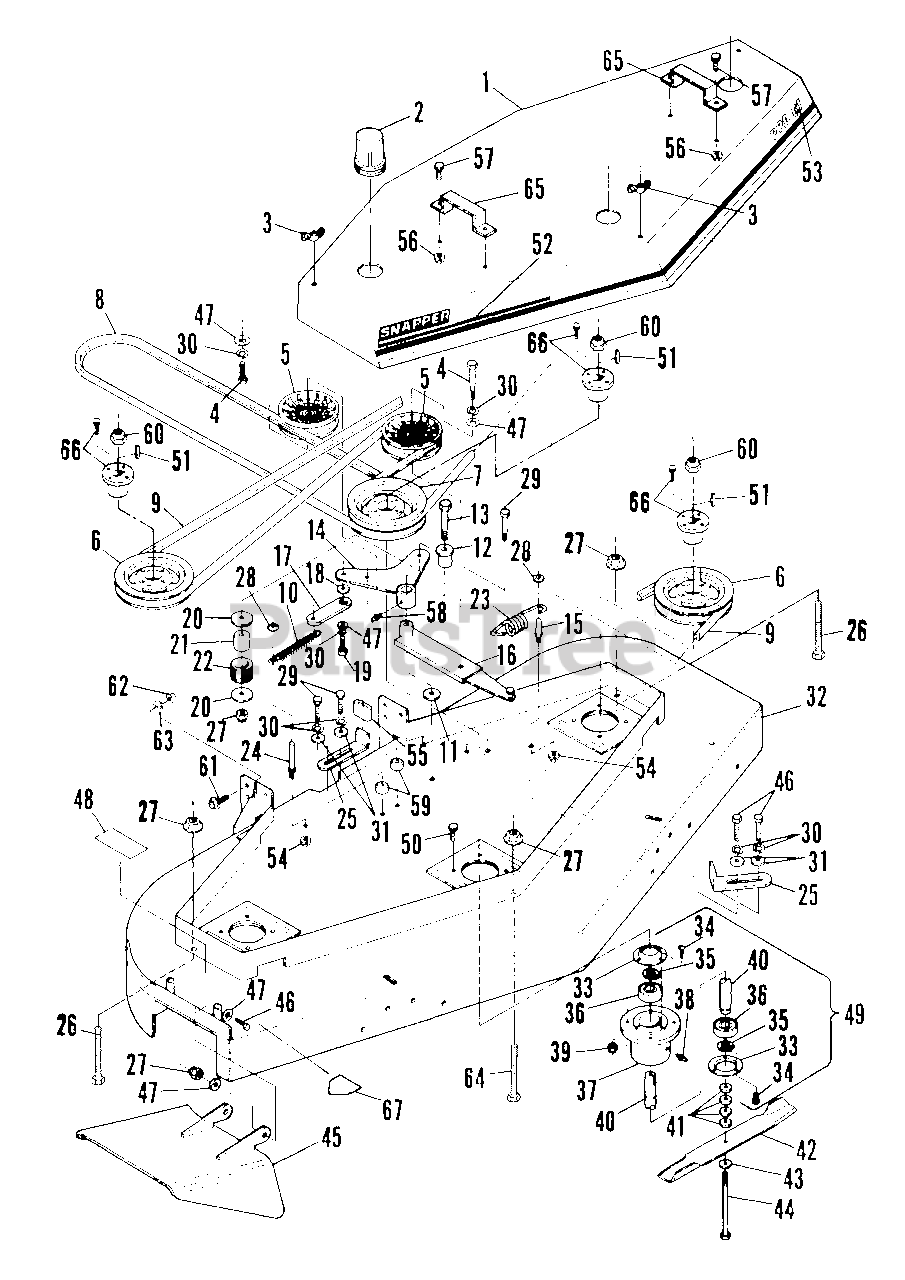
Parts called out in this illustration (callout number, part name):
1	HOOD w/DECALS 61
2	CAP, Spindle
3	NUT, 3/8-16 Wing
4	SCREW, 3/8"-16 x 3/4", Gr. 8, Hex Head
5	PULLEY, Idler
6	PULLEY, w/Set Screw
7	PULLEY, Double w/Set Screw
8	BELT, Engine to Deck 62.5"
9	BELT, Cutter Spindle
10	SPRING, Idler
11	BUSHING, Machine 14 GA
12	PIVOT, Deck Idler
13	SCREW, 3/8"-16 x 3 3/4", Hex Head Cap
14	ARM, Idler
15	STUD, Spring Mounting
16	ARM, Idler
17	ARM, Tension
19	SCREW, 3/8"-16 x 5/8", Gr. 5, Hex Head
20	WASHER, Flat (1 1/2" O.D.)
21	SPACER, Snubber
22	BUMPER, Snubber
23	SPRING, Blade HDL
24	GUIDE, Plate
25	BRACKET, Snubber
26	TAP BOLT, 3/8" x 5"
27	NUT, 3/8"-16, Flange Lock
28	RETAINER, 3/8"
29	SCREW, 3/8"-16 x 1 1/2", Hex Head Cap
30	WASHER, 3/8" Lock
31	WASHER, 5/16" Flat
33	CAP, Cutter Housing
34	SCREW, Self-Tapping, #10-24 x 1/2"
35	RING, Retaining
36	BEARING, Single Seal
37	HOUSING, Cutter
38	ZERK, 1/8 NPT
39	NUT, 3/8" Hex Nylon Ring
40	SPINDLE, Cutter
41	SPACER, Blade
42	BLADE, 21" High
43	WASHER, 5/8" Bevel
44	SCREW, 5/8"-18 x 8 1/2" Hex Head Cap
45	DEFLECTOR, Chute
46	SCREW, 3/8"-16 x 1" Hex Head Cap
47	WASHER, 3/8" Flat
48	DECAL, Caution
49	HOUSING, Cutter Assembly
50	SCREW, 3/8"-16 x 1 1/4" Hex Head Cap
51	KEY, Spindle
52	DECAL, 61 Hood
53	DECAL, Pro 61
54	NUT, 3/8"-16 Flange Lock
55	BUMPER, Snubber
56	NUT, 1/4" Hex Nylon Ring
57	SCREW, 1/4" x 5/8" Hex Head Cap
58	ZERK, 1/4"-28 Straight
59	SPACER,
60	NUT, 5/8"
61	BOLT, 1/2"-13 x 1 1/4" Hex Flange Lock
62	NUT, 1/2"-13 Hex
63	WASHER, 1/2" Lock
64	TAP BOLT, 3/8" x 4"
65	HANDLE, Hood
66	BUSHING, Taperlock
67	DECAL, Warning
